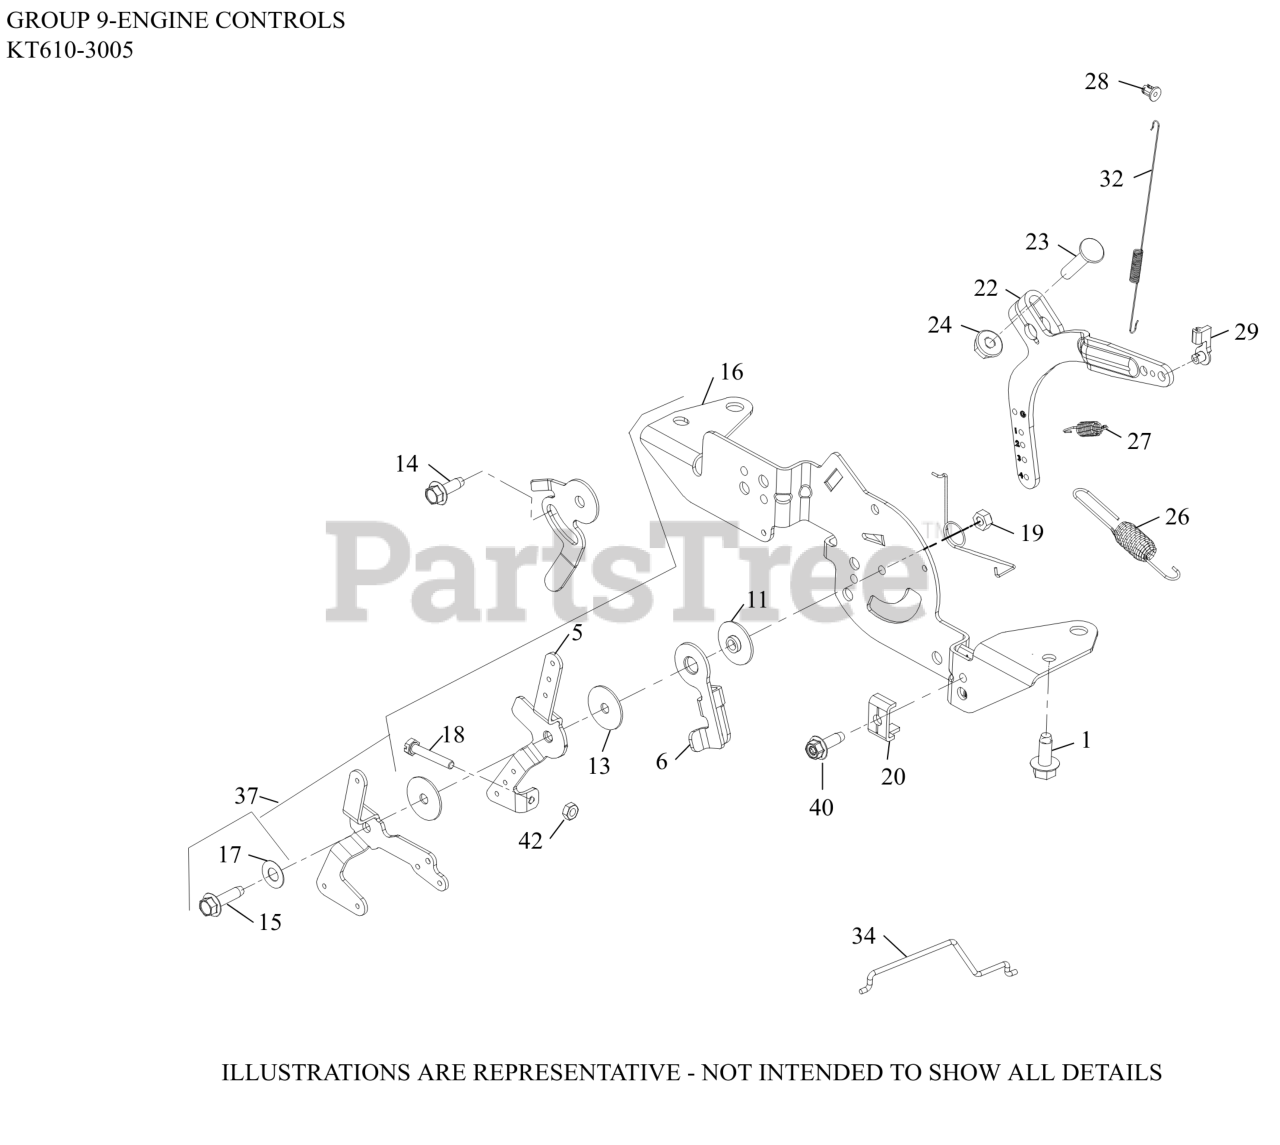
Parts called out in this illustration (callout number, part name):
1	SCREW, THREAD FORMING
5	LEVER, THROTTLE CONTROL
6	LEVER, THROTTLE ACTUATOR
11	SPACER, CONTROL ASSEMBLY
13	WASHER, FLAT 5 MM
14	SCREW, THREAD FORMING
15	SCREW, THD FRM-USE 25 086 473-S
16	BRACKET, SPEED CONTROL
17	WASHER, SPRING 1/4"
18	SCREW, SLT HD CAP M4X0.7X25
19	NUT, LOCK M5X.8
20	CLAMP, CABLE-(#2523753S)
22	LEVER, GOVERNOR - (#2409069S)
23	BOLT, RD HD SQ NECK M6X1.0X25
24	NUT, FLG M6X1.0
26	SPRING, GOVERNOR (ORANGE)
27	SPRING, GOVERNED IDLE
28	BUSHING, LINKAGE RETAINING
29	BUSHING, THROTTLE LINKAGE
32	SPRING, LINKAGE
34	LINKAGE, THROTTLE
37	SPEED CONTROL, ASSEMBLY
40	SCREW, THREAD FORMING
42	NUT, M4X0.7
